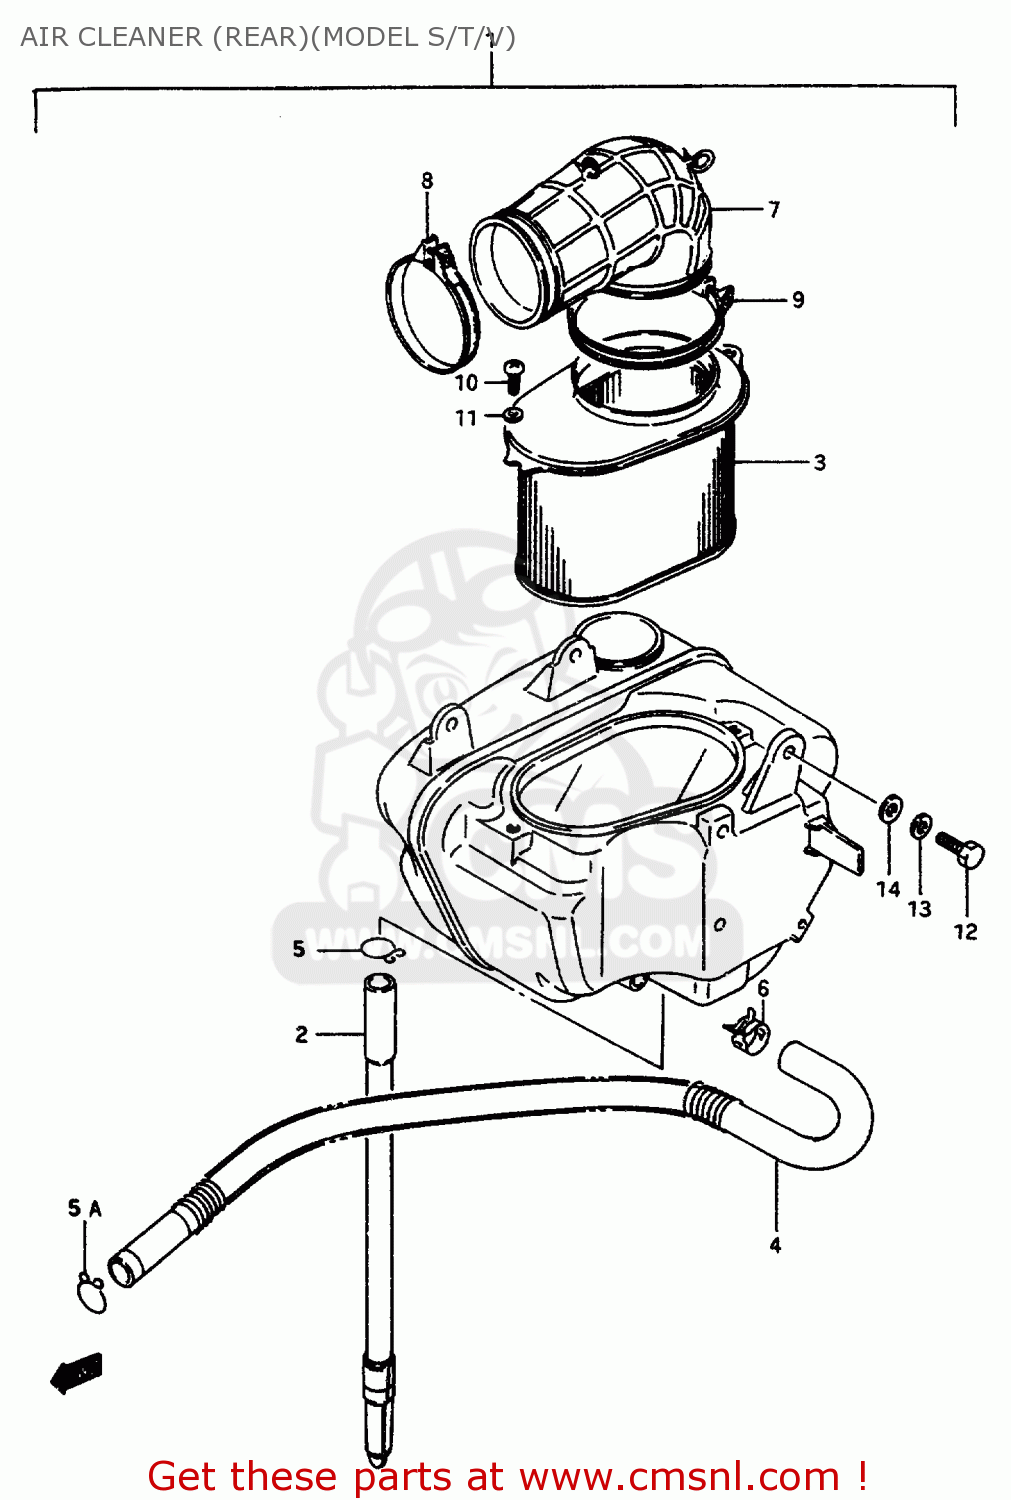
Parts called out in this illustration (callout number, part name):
1	CLEANER ASSY,AIR RR
2	TUBE,DRAIN
3	FILTER ASSY
4	TUBE SET,BREATHER
5	CLIP
5A	CLIP
6	CLIP
7	TUBE,AIR CLEANER OUTLET
8	CLAMP
9	CLAMP
10	SCREW
11	LOCK,WASHER
12	BOLT
13	WASHER,LOCK
14	WASHER(6.5X16X1.2)
